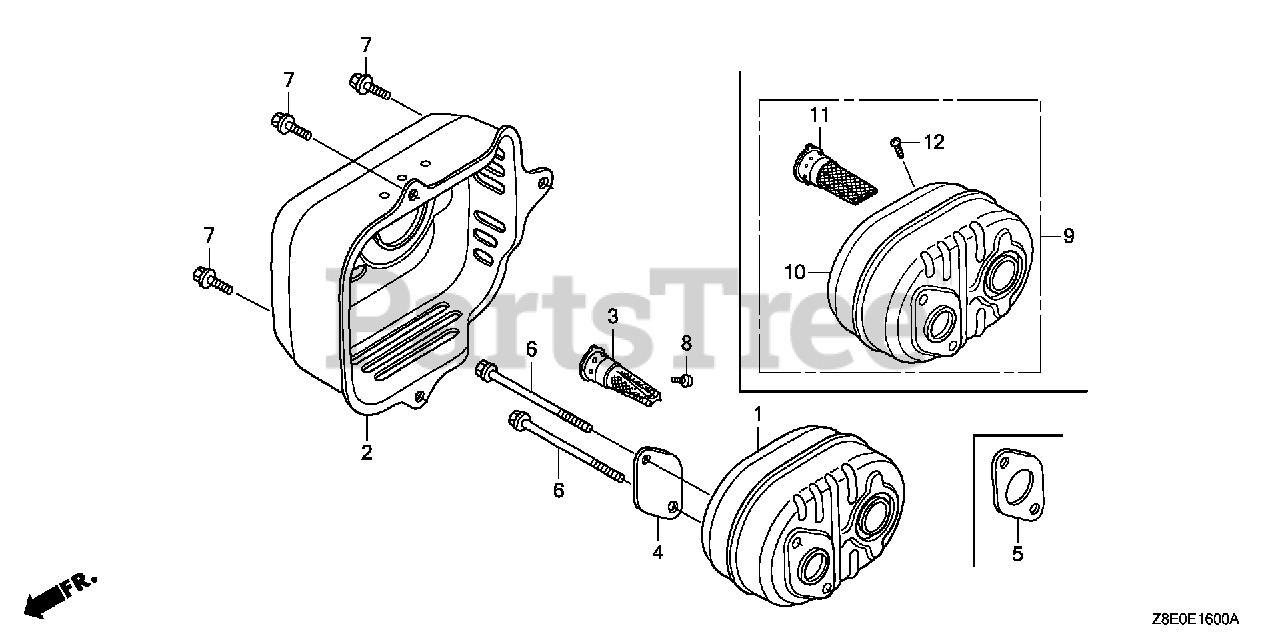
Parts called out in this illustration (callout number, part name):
1	MUFFLER
2	PROTECTOR, MUFFLER
3	ARRESTER, SPARK
4	PLATE, ARRESTER NUMBER
5	GASKET, MUFFLER
6	BOLT, FLANGE (6X79) (CT200)
7	BOLT, FLANGE (6X12) (CT200)
8	SCREW, TAPPING (4X6)
